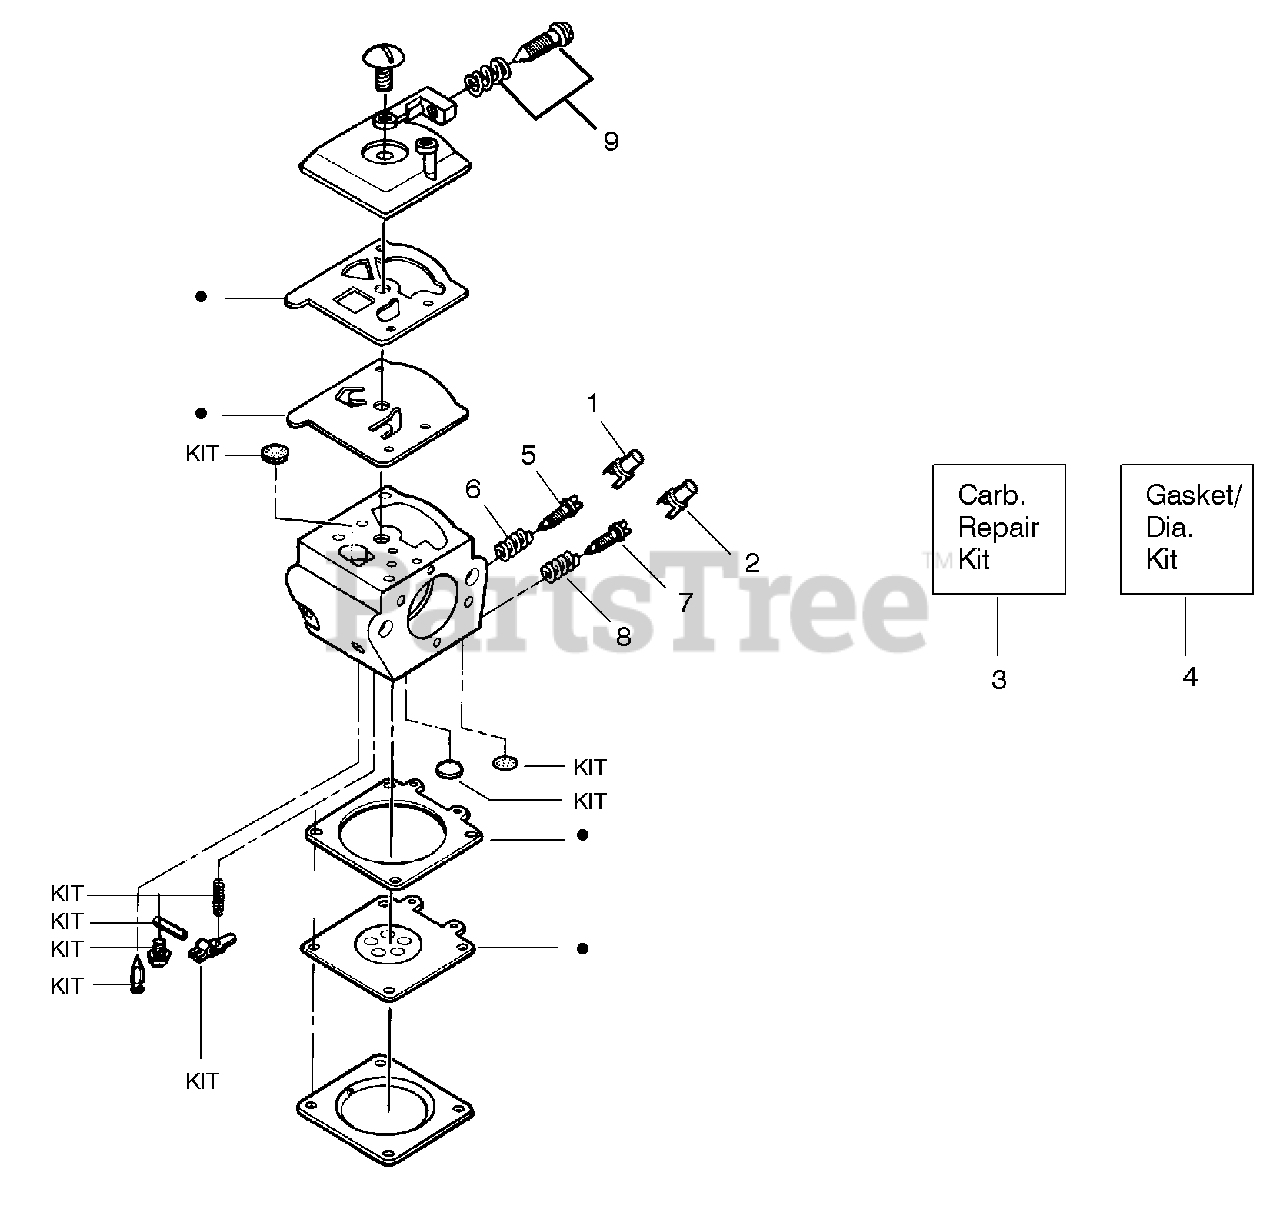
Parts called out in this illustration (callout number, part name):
1	Limiter Cap-High
2	Limiter Cap-Low
3	Carburetor Repair Kit
4	Gasket Diaphragm Kit
5	Needle-Low Speed
6	Needle Spring-Low Speed
7	Needle-High Speed
8	Needle Spring-High Speed
9	Idle Screw/Spring Kit
